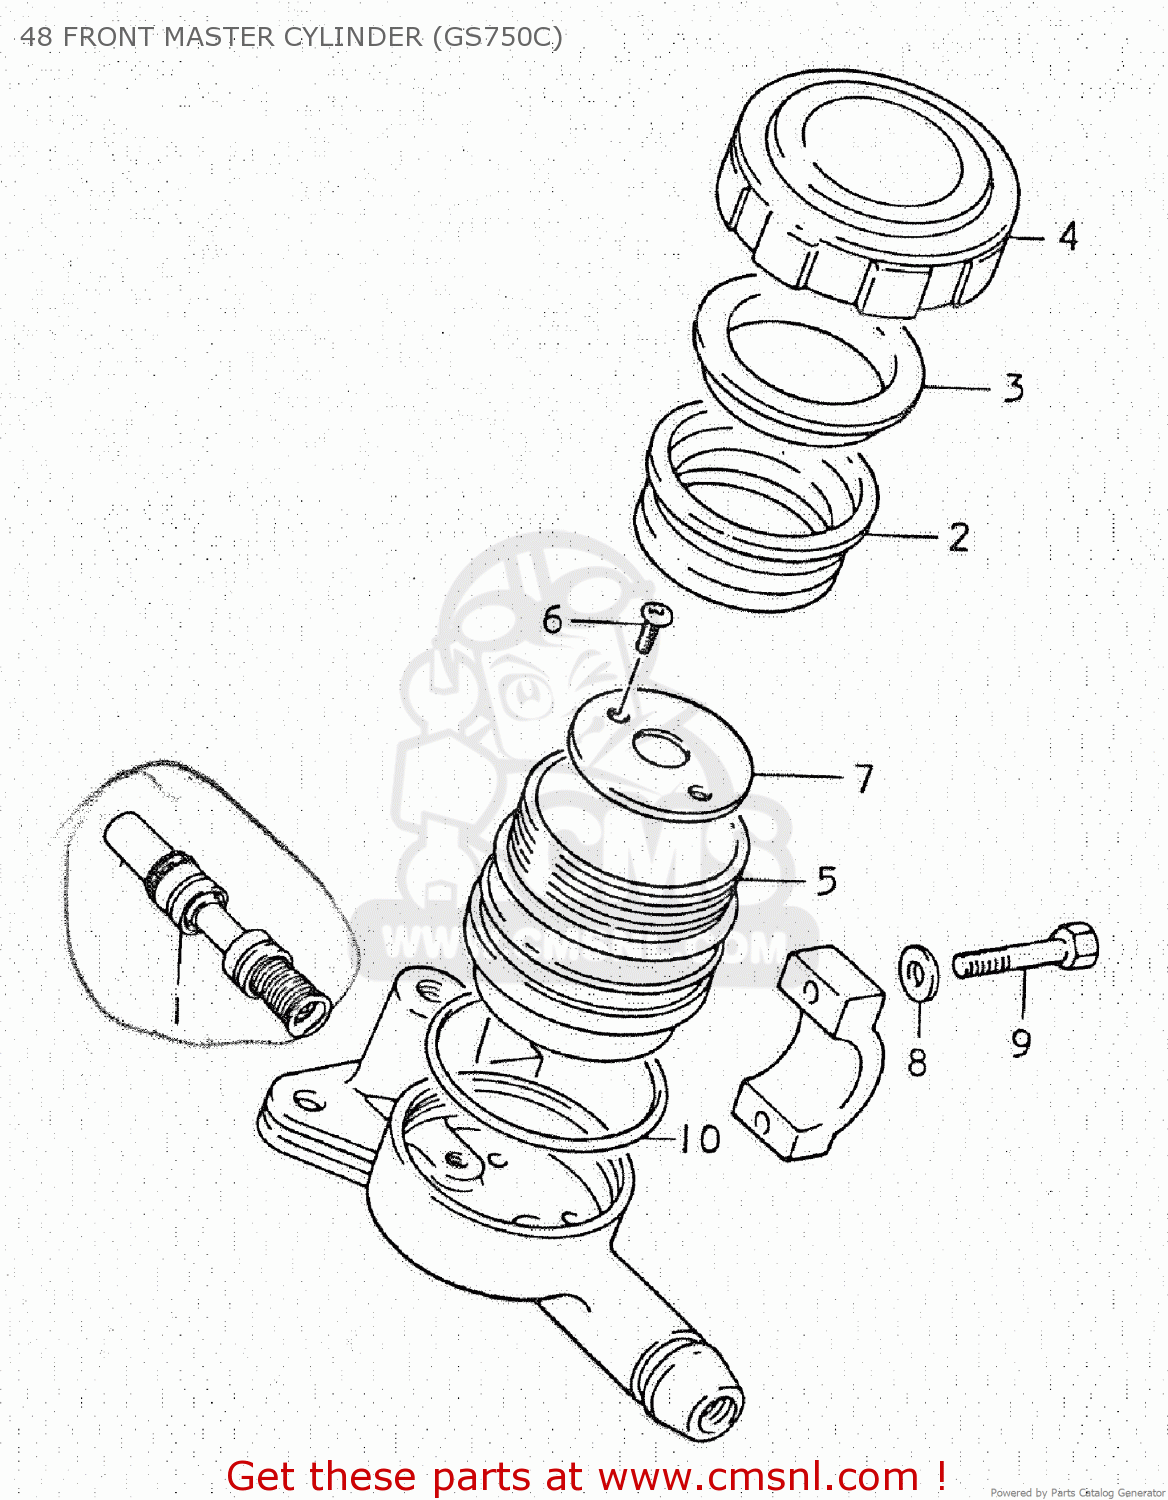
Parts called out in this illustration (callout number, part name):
1	CYLINDER ASSEMBLY,FRONT MASTER
2	DIAPHRAGM,MASTER CYLINDER
3	PLATE,DIAPHRAGM
4	CAP
5	RESERVOIR
6	SCREW
7	PLATE
8	WASHER
9	BOLT
10	O RING
